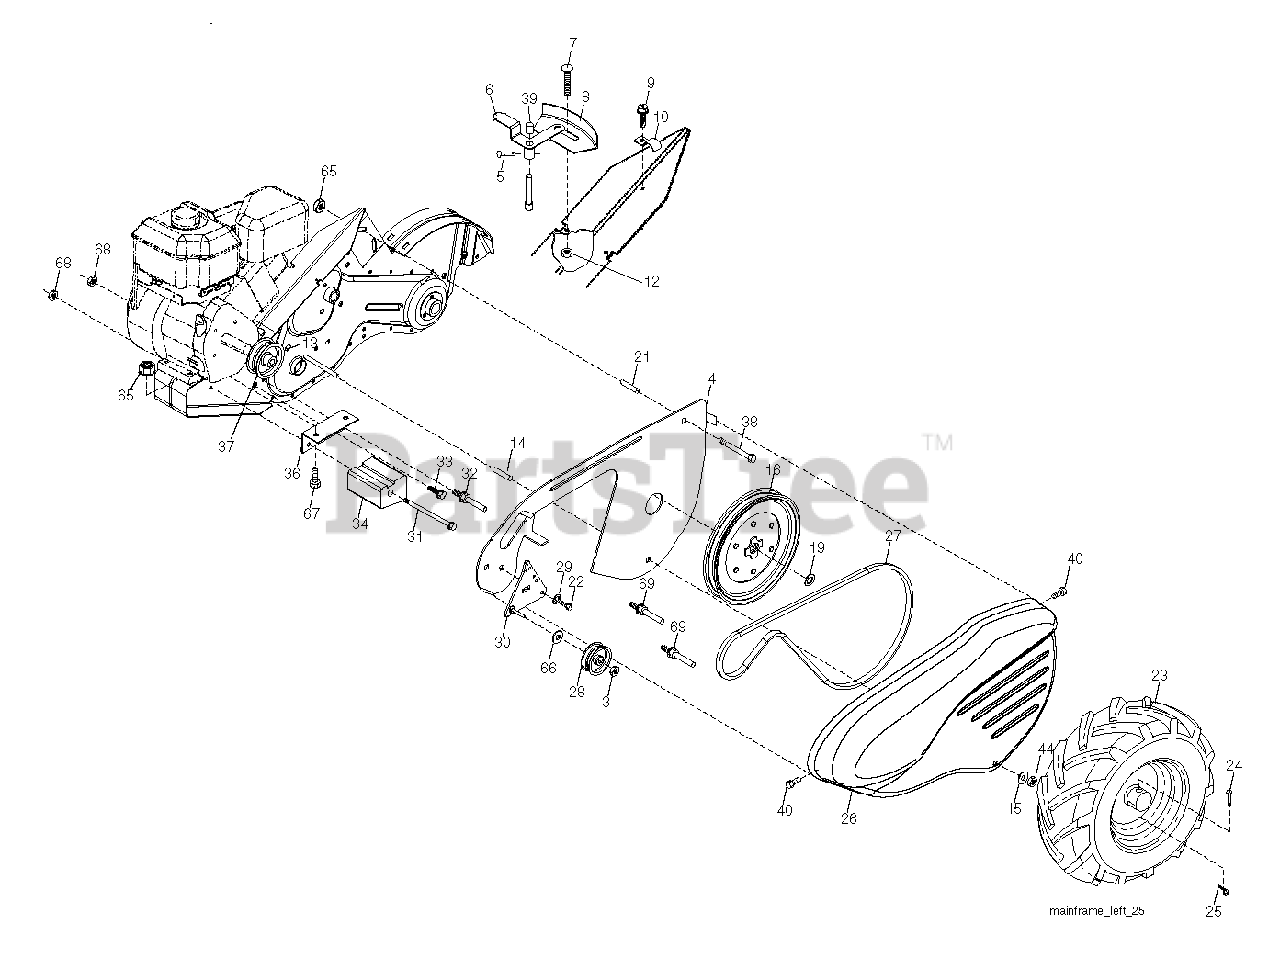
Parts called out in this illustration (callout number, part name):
3	LOCKNUT
4	SHIELD.INNER.BELT.GUARD.RT
5	PIN.SPIROL.FLARED
6	LEVER ASM CRT
9	TAPPING SCREW
10	CONDUIT CLIP T
12	NUT
15	WASHER
16	SHEAVE, TRANSMISSION
19	RETAINING RING LT
21	SPACER-SPLIT.327 X .42
24	RIVET,DRILLED
25	RETAINER M
26	GUARD.BELT.TILLER.RT.RED
27	V-BELT
28	PULLEY-IDLER TI
30	BRACKET.ASM.IDLER
31	BOLT.FIN.HEX.3/8-16UNC
32	SHIFT ARM CRT
33	BOLT
34	COUNTERWEIGHT.LH.CRT
36	BRACKET LH CRT
37	ENGINE PULLEY
38	BOLT
39	CAP.PLUNGER.BLACK
40	SCREW.HEX.WSH.SLT.#10-24X.50
44	NUT.71038.31-18.HEX.NYLOCK
65	LOCKNUT-FLANGE 5/16-18
66	WASHER
67	BOLT
69	KEEPER.BELT.ENGINE
